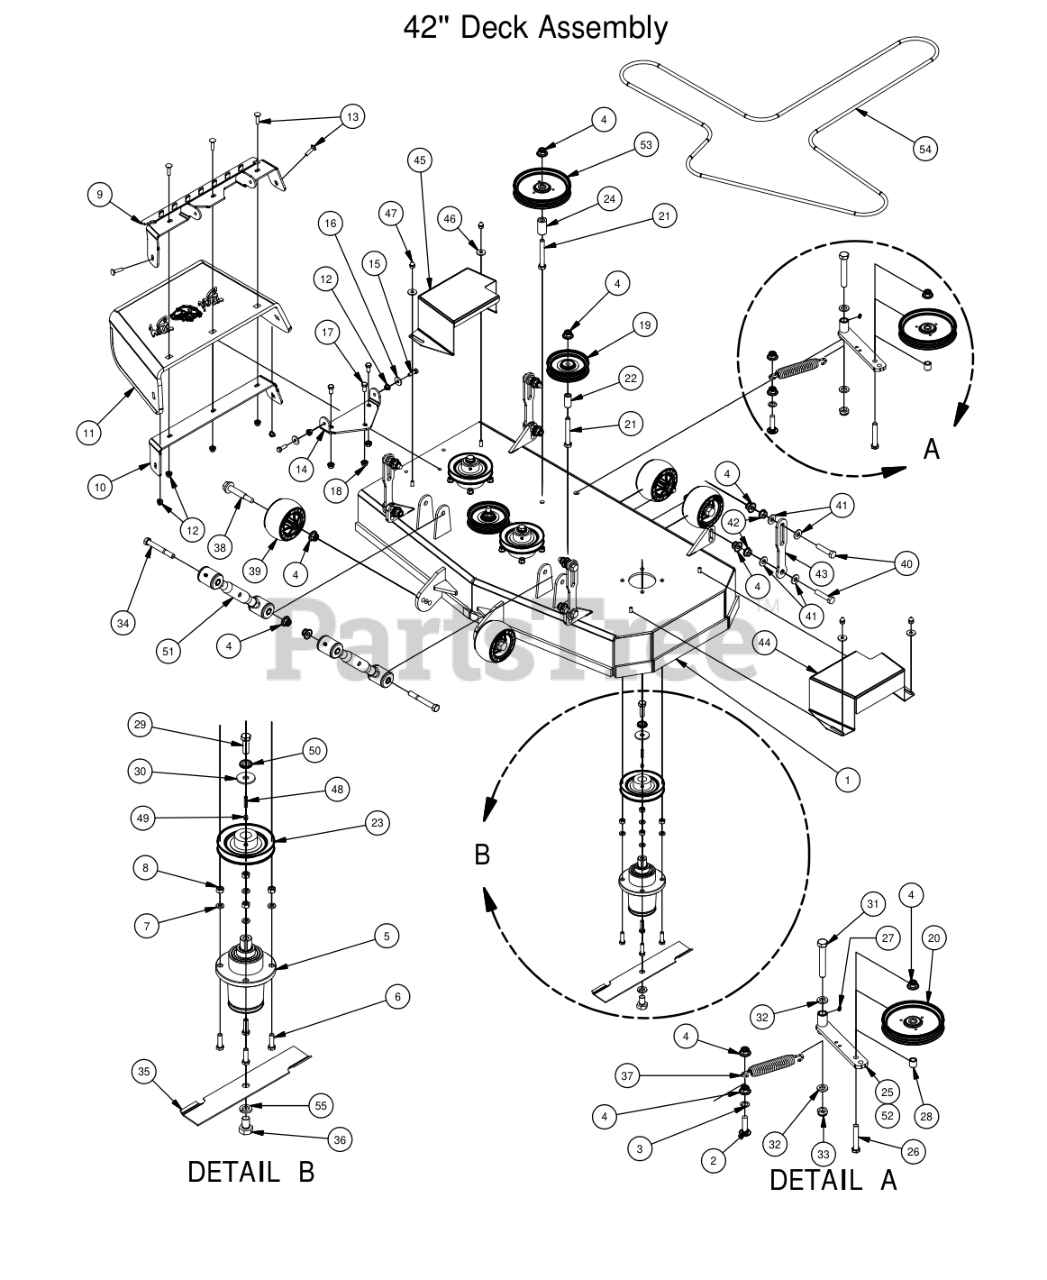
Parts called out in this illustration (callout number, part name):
1	42" Compact Outlaw Deck-Welded Shell
2	1/2 x 2" Carriage Bolt
3	.517 Square Hole Round Washer
4	1/2-13 Nylon Flange Nut
5	Spindle Assembly
6	3/8" x 1 1/4" Hex Bolt
7	3/8" Lock Washer
8	3/8" Hex Nut
9	Discharge Upper Chute Bracket
10	Discharge Lower Chute Bracket
11	Rubber Discharge Chute
12	5/16" Nylon Flange Nut
13	5/16" x 1 1/4" Carriage Bolt
14	Discharge Chute Hanger (Deck Mounted)
15	5/16" x 1" Bolt
16	.360 ID Plastic Washer
17	3/8" x 3/4" Hex Bolt
18	3/8" Flange Nut
19	4 3/4" Idler Pulley
20	5-3/4 Idler Pulley-Don Dye
21	1/2 x 3 1/2 Flange Bolt Grade 8
22	.502 ID X.750 OD X 1.500 Long Spacer
23	5" Spindle Deck Pulley
24	1 3/4" Pulley Spacer
25	Deck Idler
26	1/2-13 x GR 5 Hex Bolt Zinc
27	1/4" Press in Grease Fitting
28	Spacer 3/4 OD x 1/2 ID x 3\4 Length
29	1/2"-20 x 1 1/2 - Grade 5 Fine Thread Bolt
30	1/2 Belleville Washer
31	5/8" x 4" Hex Bolt
32	.630 ID X 1.122 OD X .142 THK Flat Washer Nylon
33	5/8" Nylock (1/2 Jam)
34	1/2" x 4" Bolt (Grade 8)
35	42" High Lift Blade
36	5/8" x 1 1/2" Grade 8 Hex Bolt (Fine)
37	2015 Deck Idler Spring Outlaws
38	Deck Wheel Bolt
39	Anti-Scalp Rollers
40	1/2-13X 2-1/4 GR Hex Bolts
41	.505 Nylon Spacer
42	1/2" Flange Nut
43	Deck_Hanging_Tab longer
44	Pulley Cover Compact Outlaw-Left
45	Pulley Cover Compact Outlaw-Right
46	.360 ID Plastic Washer-Black
47	Acorn nut-pulley Cover
48	1/4" x 1" Key
49	5/16 Set Screw
50	1/2" Lock Washer Zinc
51	Turnbuckle
52	Deck Idler Assembly (Parts 4,25,26,27,28,53)
53	5-3/4 Idler Pulley
54	B 138 Deck Belt
55	5/8" Lock Washer
